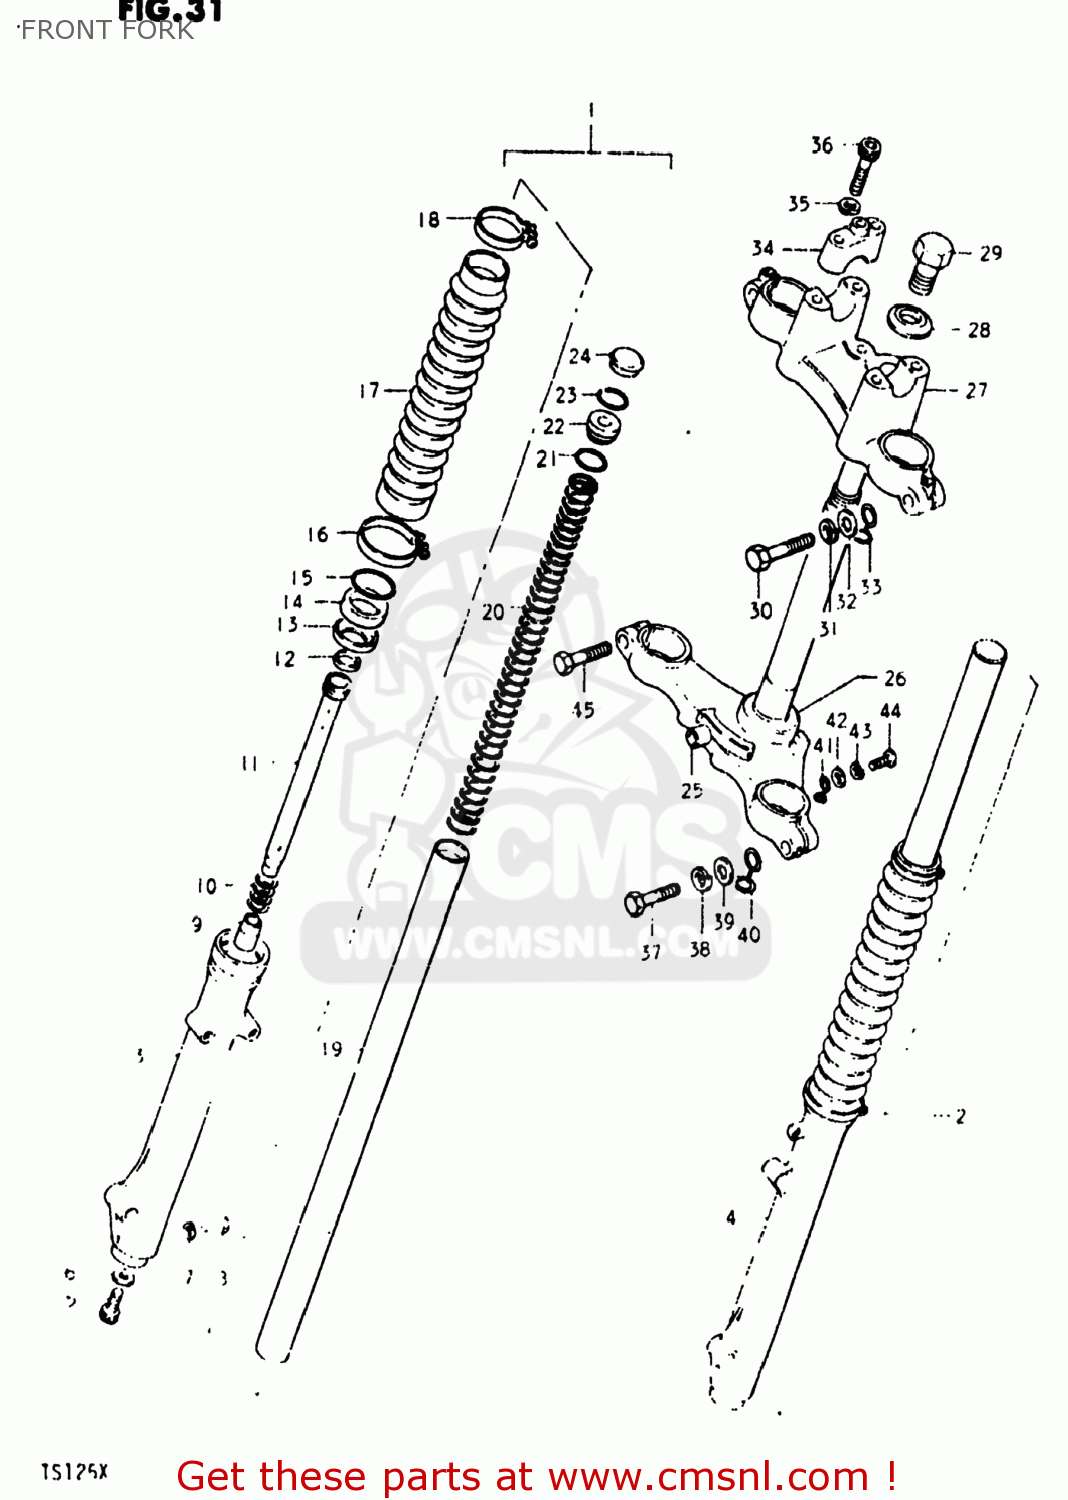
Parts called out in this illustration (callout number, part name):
1	DAMPER ASSEMBLY,RIGHT
2	DAMPER ASSEMBLY,LEFT
3	TUBE,FORK,OUTER,RIGHT
4	TUBE,FORK,LEFT,OUTER
5	BOLT(8X27)
6	GASKET (NAS)
7	GASKET,DRAIN,PLUG (NAS)
8	BOLT(6X8)
9	PIECE,OIL LOCK
10	SPRING,REBOUND
11	CYLINDER,FRONT FORK
12	RING,PISTON
13	WASHER,FRONT FORK OIL SEAL
14	OIL SEAL,FRONT FORK
15	CIRCLIP,FORK OIL SEAL
16	CLAMP
17	BOOT
18	BAND
19	TUBE,FORK,INNER
20	SPRING,FRONT FORK
21	O RING
22	SEAT,SPRING
23	RING,STOPPER
24	CAP,FRONT FORK
25	STEM,STEERING
26	RACE,STEERING OUTER LWR
27	HEAD,STEERING STEM
28	WASHER(10.5X30X2.3)
29	BOLT
30	BOLT
31	LOCK WASHER
32	WASHER
33	CLIP
34	HOLDER,HANDLEBAR
35	LOCK WASHER
36	BOLT 8X35
37	BOLT 12X45
38	WASHER,LOCK 12
39	WASHER
40	CLIP
41	CLIP
42	WASHER
43	LOCK WASHER
44	SCREW 6X12
45	BOLT
